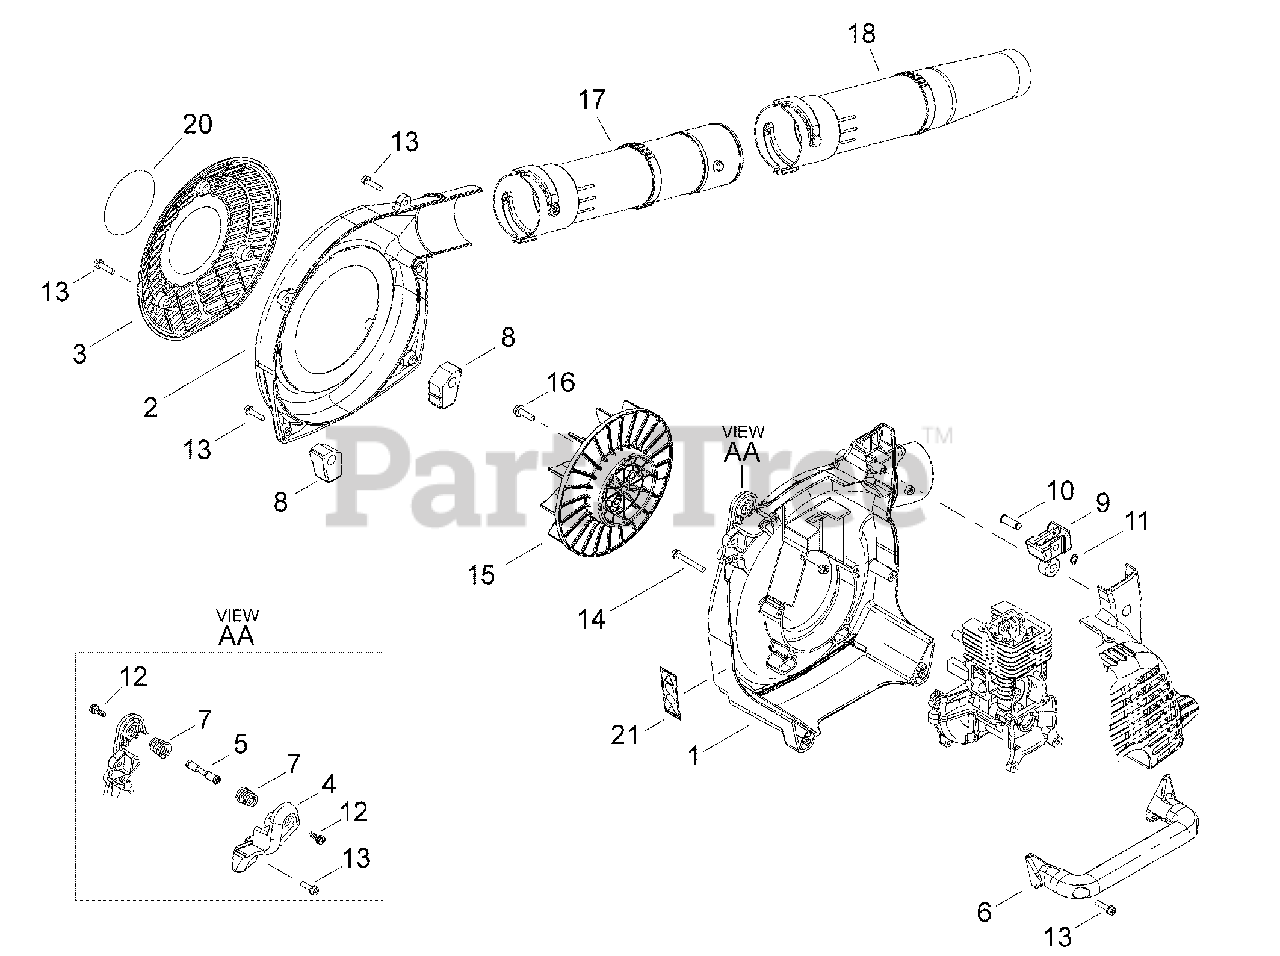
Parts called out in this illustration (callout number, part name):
1	COVER, FAN - RIGHT
2	COVER, FAN - LEFT
3	COVER, INTAKE
4	COVER, HANDLE
5	NUT
6	HANDLE - LOWER
7	SPRING
8	CUSHION - REAR
9	CUSHION - REAR
10	PIN - LOCKING
11	RING, RETAINING - 8
12	SCREW - 5X16
13	BOLT - 5X20
14	SCREW - 5X40
15	FAN
16	SCREW - 6X20
17	TUBE, BLOWER
18	NOZZLE
20	LABEL - MODEL A3000
21	LABEL - CAUTION
